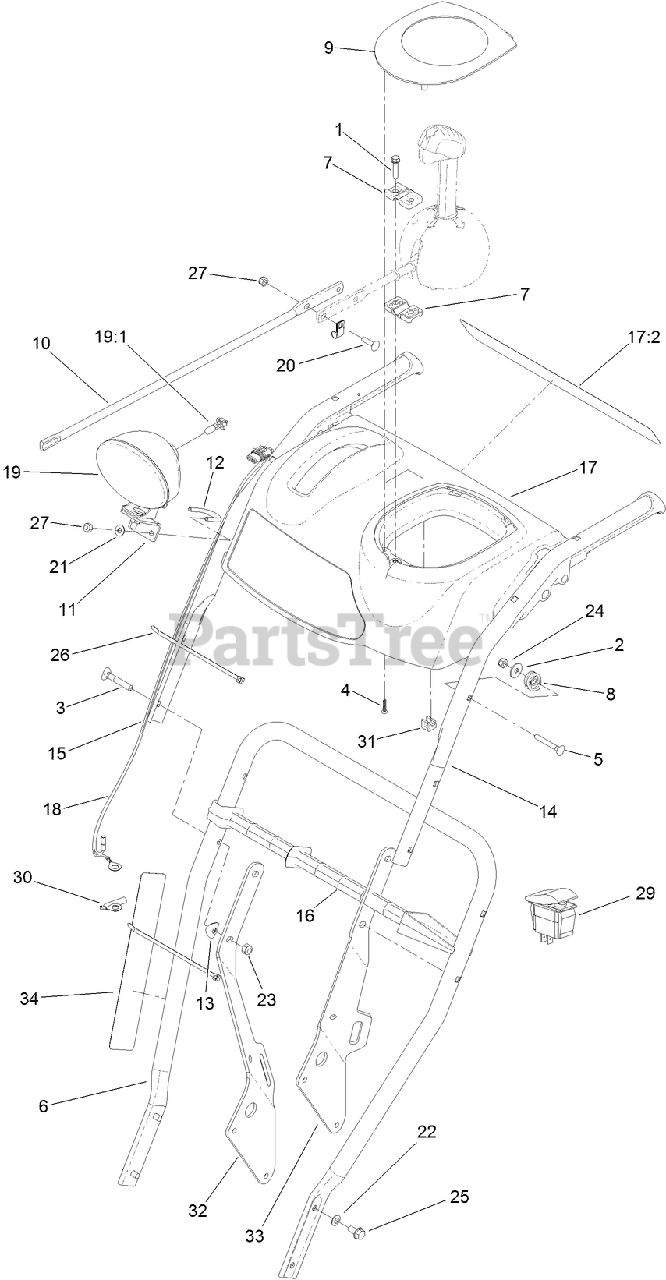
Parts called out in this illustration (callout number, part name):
1	SCREW-PLASTITE
2	WASHER-PLAIN
3	SCREW-HANDLE
4	SCREW-PPH
5	SCREW
6	HANDLE-LOWER
7	SUPPORT-ROD
8	CLAMP-CABLE
9	COVER-PANEL, CONTROL
10	ROD-CHUTE, FRONT
11	BRACKET-LIGHT
12	CLAMP-LIGHT
13	WASHER
14	HANDLE-UPPER, LH
15	HANDLE-UPPER, RH
16	STICK-CLEANOUT
17	CONTROL PANEL ASM
17:2	DECAL-CONTROL
18	HARNESS-WIRE, HEATED GRIPS
19	HEADLAMP ASM
19:1	LAMP-12 VOLT
20	SCREW-CARR
21	WASHER-FLAT
22	WASHER-BELLEVILLE
23	NUT-LOCK, NI
24	NUT-LOCK, NI
25	SCREW-HWHTF
26	TIE-CABLE
27	NUT-LOCK, NI
29	SWITCH-ROCKER, OFF-NONE-ON
30	HARNESS-WIRE, GROUND JUMPER
31	CLIP-EDGE
32	BRACE-HANDLE, LH
33	BRACE-HANDLE, RH
34	DECAL-TAPE, REFLECTIVE
